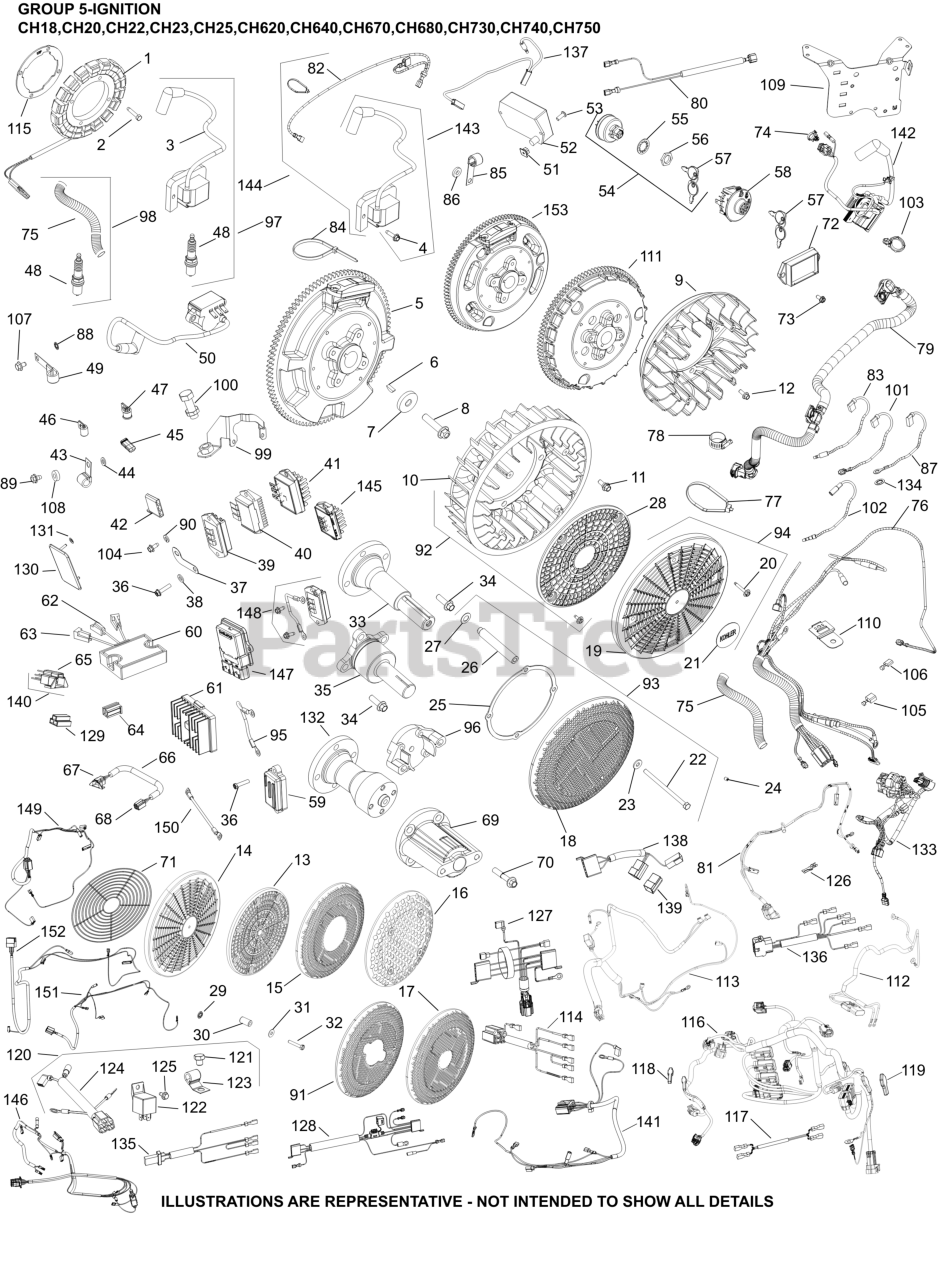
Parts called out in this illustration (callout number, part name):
1	KIT, 15 / 20 AMP STATOR
2	SCREW, THREAD FORMING
3	MODULE, MDI
4	SCREW, THREAD FORMING
6	KEY, 3/16" X 5/8"
7	WASHER, FLAT
8	SCREW, HEX FLANGE
10	FAN-USE 24 755 253-S
11	BOLT, SHOULDER
14	SCREEN, GRASS
20	SCREW, FLG SEMS M4x.7x25
36	SCREW, HEX FLANGE HI-LO
42	CONNECTOR
43	CLIP, CABLE
48	PLUG, SPARK (PRO SERIES)
57	KEY, SET OF 2
58	KIT, KEY SWITCH (SNAP-IN)
76	HARNESS, WIRING ASSEMBLY
82	LEAD, DUPLEX
83	LEAD, OIL SENTRY
87	LEAD, 20/25 AMP B+
94	KIT GRASS SCREEN
104	SCREW, THREAD FORMING
145	REGULATOR, RECTIFIER (20-30AMP,FW W/OVP)
NI	FLYWHEEL ASSEMBLY (LW)
